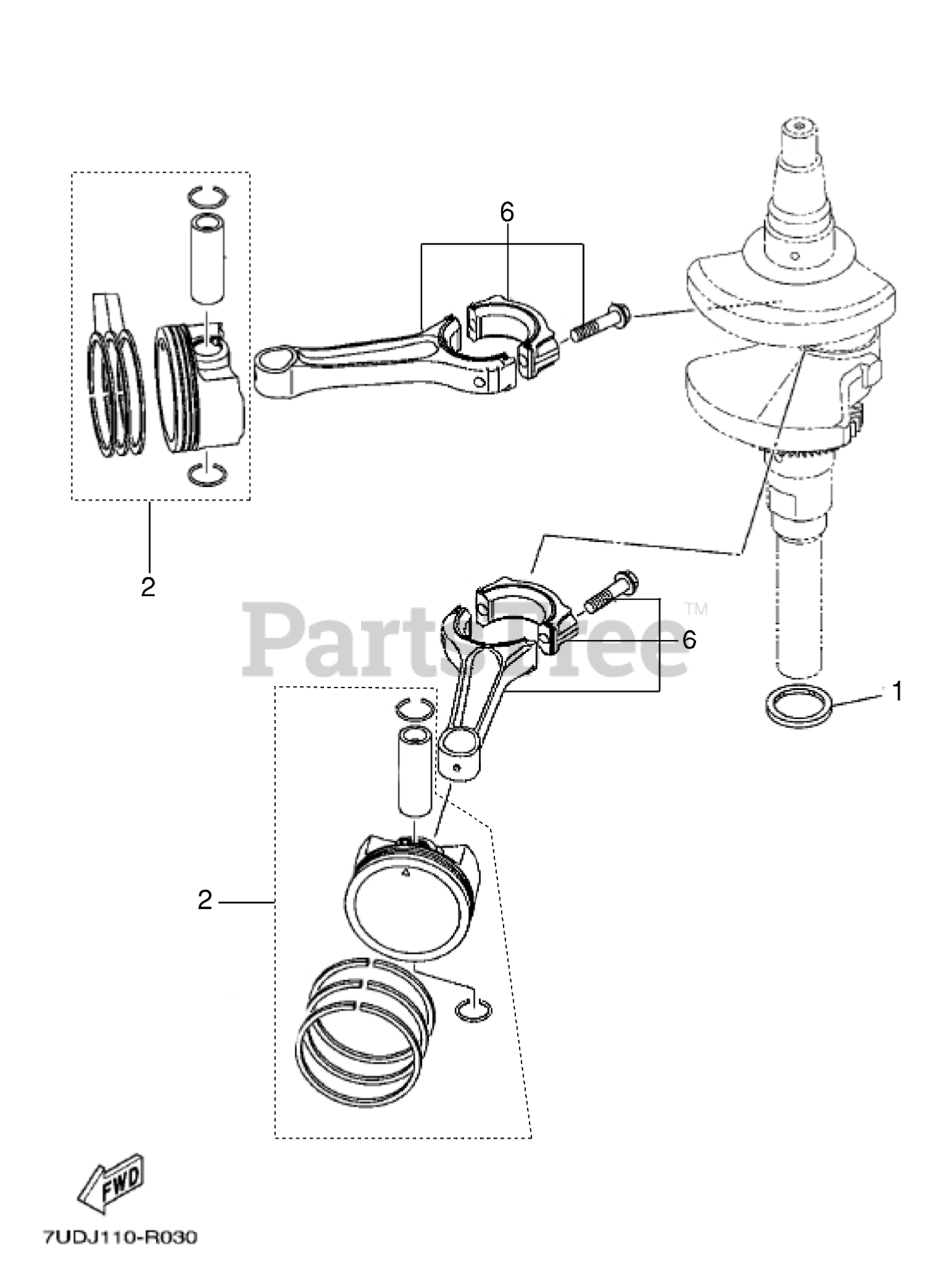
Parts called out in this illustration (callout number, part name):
1	COLLAR YAMAHA PN: 7UD-E1478-0
2	PISTON ASSY
6	CONNECTING ROD ASSY YAMAHA PN
